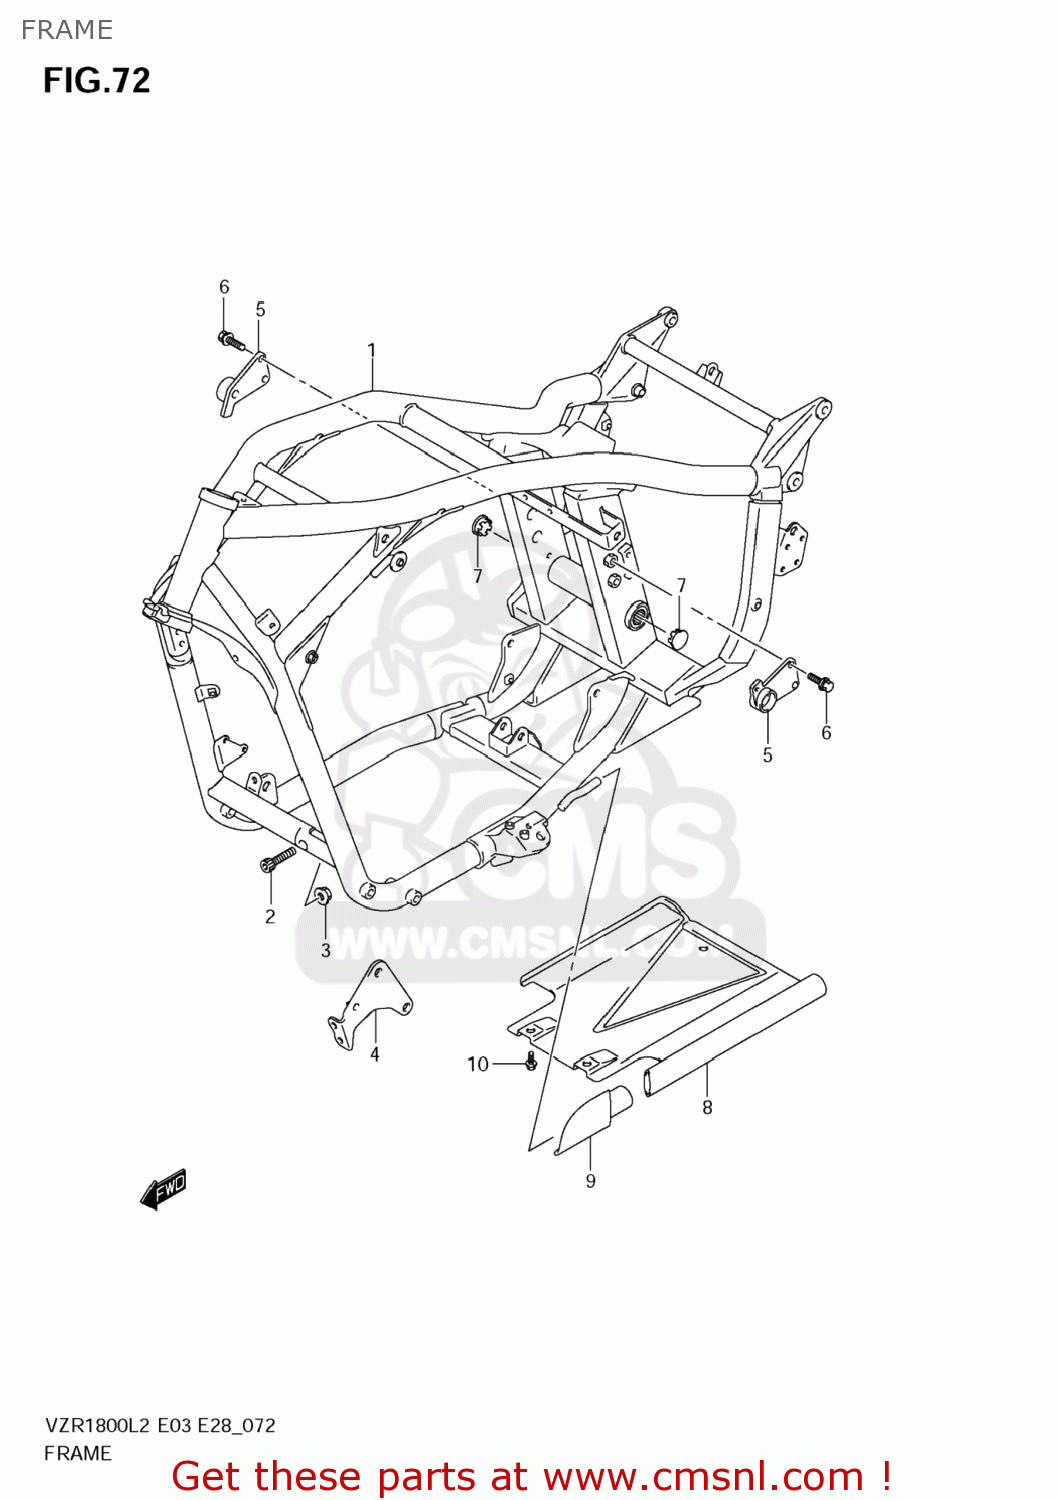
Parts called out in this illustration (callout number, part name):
1	FRAME(BLACK)
2	BOLT
3	NUT
4	PLATE,ENG MTG FR,L
5	BRACKET,ENGINE MOUNTING RR
6	BOLT
7	CAP,ENG MTG BOLT
8	COVER,UNDER
9	RUBBER,UNDER COVER
10	BOLT
